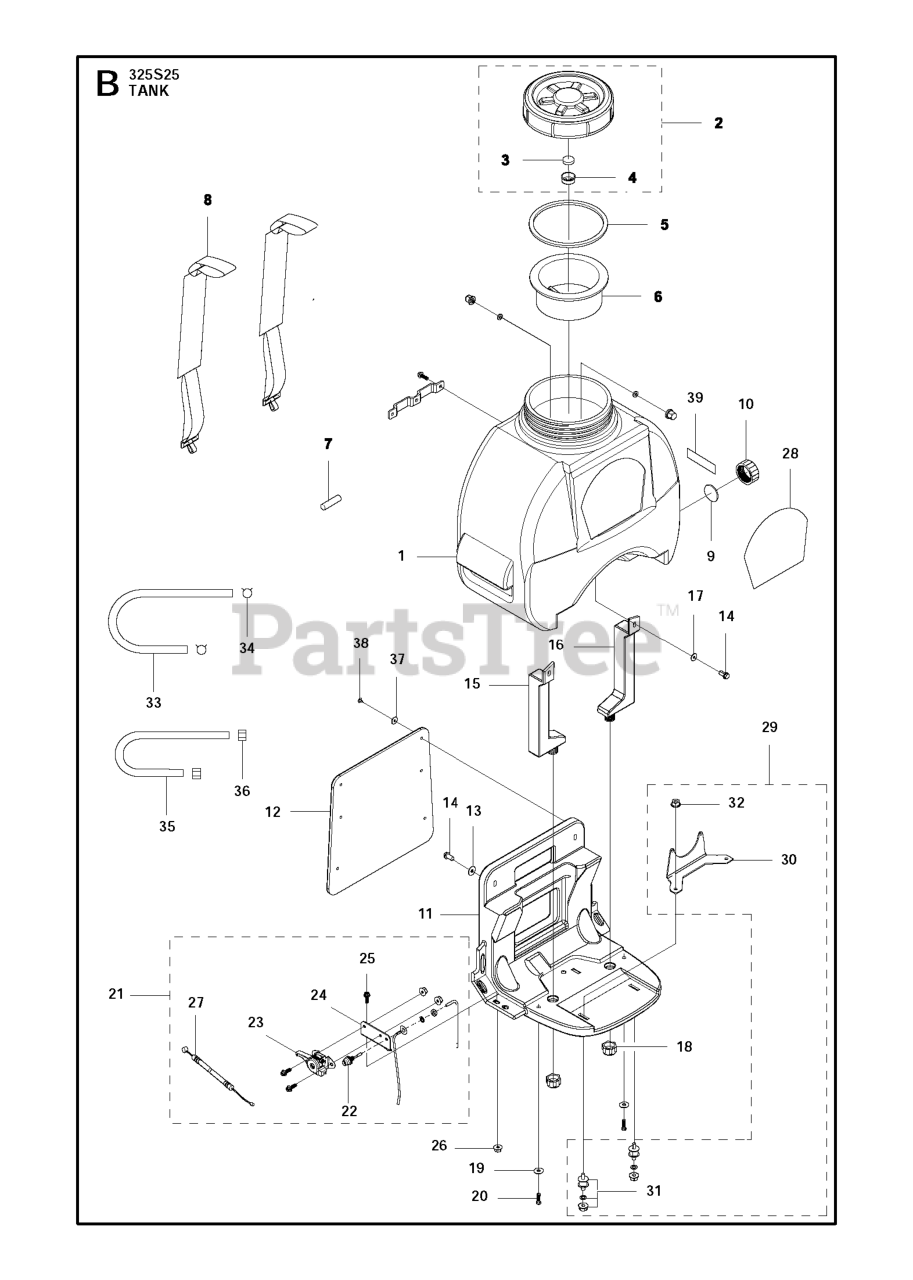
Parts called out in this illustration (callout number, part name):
1	CHEMICAL TANK 25L (FAT TANK)
2	CAP CHEMICAL
4	CAP OF SPONGE
8	KNAPSACK STRAP
9	CAP OF PACKING
12	CUSHION PAD
21	THROTTLE SET
27	CABLE COMP
28	NAME LABEL
29	STAY ENGINE ASSY
30	STAY ENGINE
33	INHAL PIPE
35	BACKWATER PIPE
39	ATTENT LABEL
